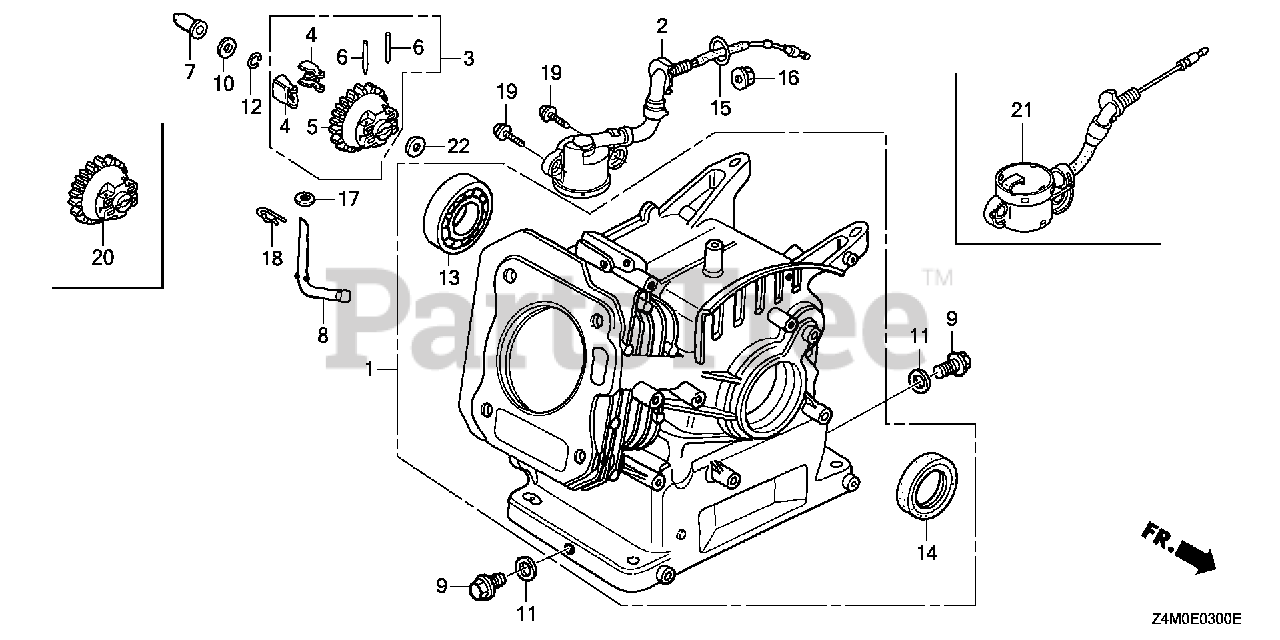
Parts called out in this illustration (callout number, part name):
1	CYLINDER ASSY.
3	GOVERNOR ASSY.
4	WEIGHT, GOVERNOR
5	HOLDER, GOVERNOR WEIGHT
6	PIN, GOVERNOR WEIGHT
7	SLIDER, GOVERNOR
8	SHAFT, GOVERNOR ARM
9	BOLT, DRAIN PLUG
11	WASHER, DRAIN PLUG (10.2MM)
12	CLIP, GOVERNOR HOLDER
13	BEARING, RADIAL BALL (6205)
13	BEARING, RADIAL BALL (6205) (NSK)
14	OIL SEAL (25X41X6)
14	OIL SEAL (25X41X6) (ARAI) (NOT AVAILABLE)
17	WASHER, PLAIN (6MM)
18	PIN, LOCK (8MM)
22	WASHER, PLAIN (6MM)
